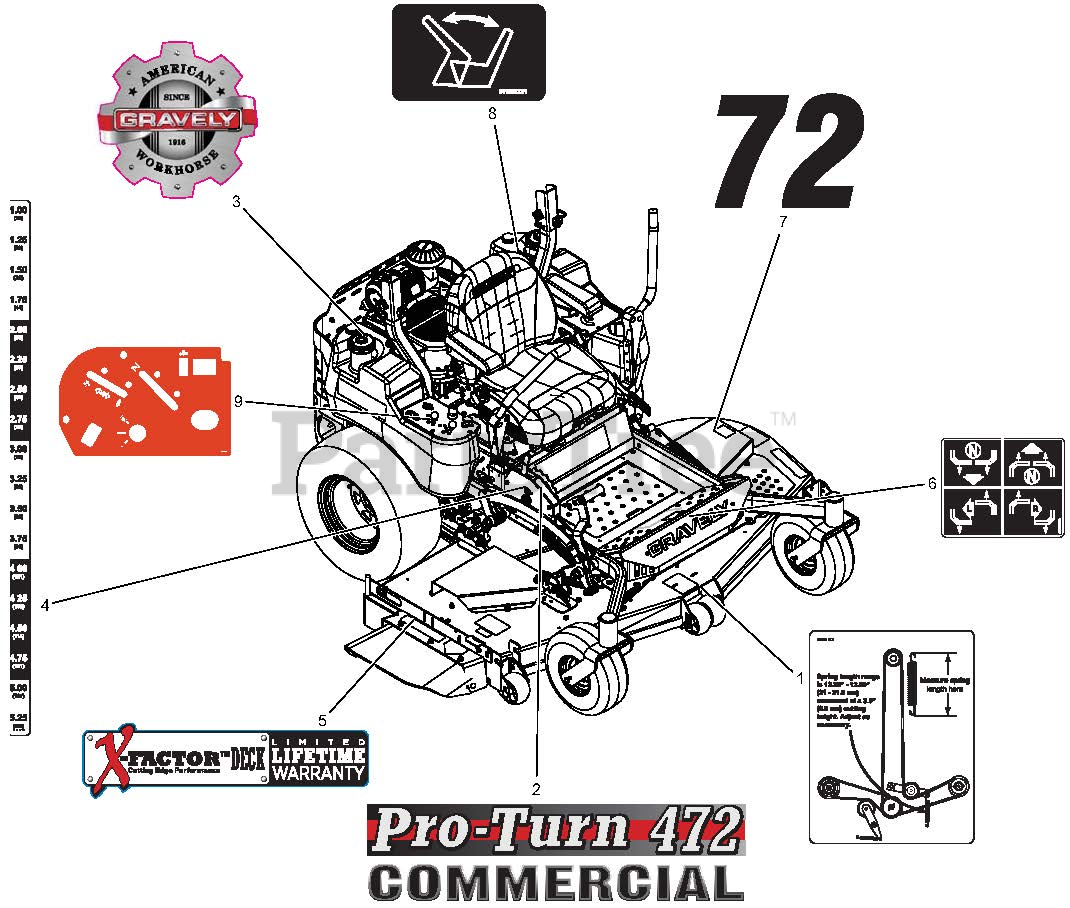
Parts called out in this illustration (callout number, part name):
1	DECAL, BELT DIAGRAM
2	DECAL, PRO-TURN 472 COMMERCIAL
3	DECAL, GRAVELY HERITAGE-LARGE
4	DECAL, PT400 HEIGHT OF CUT
5	DECAL, X-FACTOR DECK
6	DECAL, INSTRUCTIONAL - STEERING
7	DECAL, 72"
8	DECAL, SEAT RELEASE
9	DECAL, NON-EFI CONTROL PANEL
